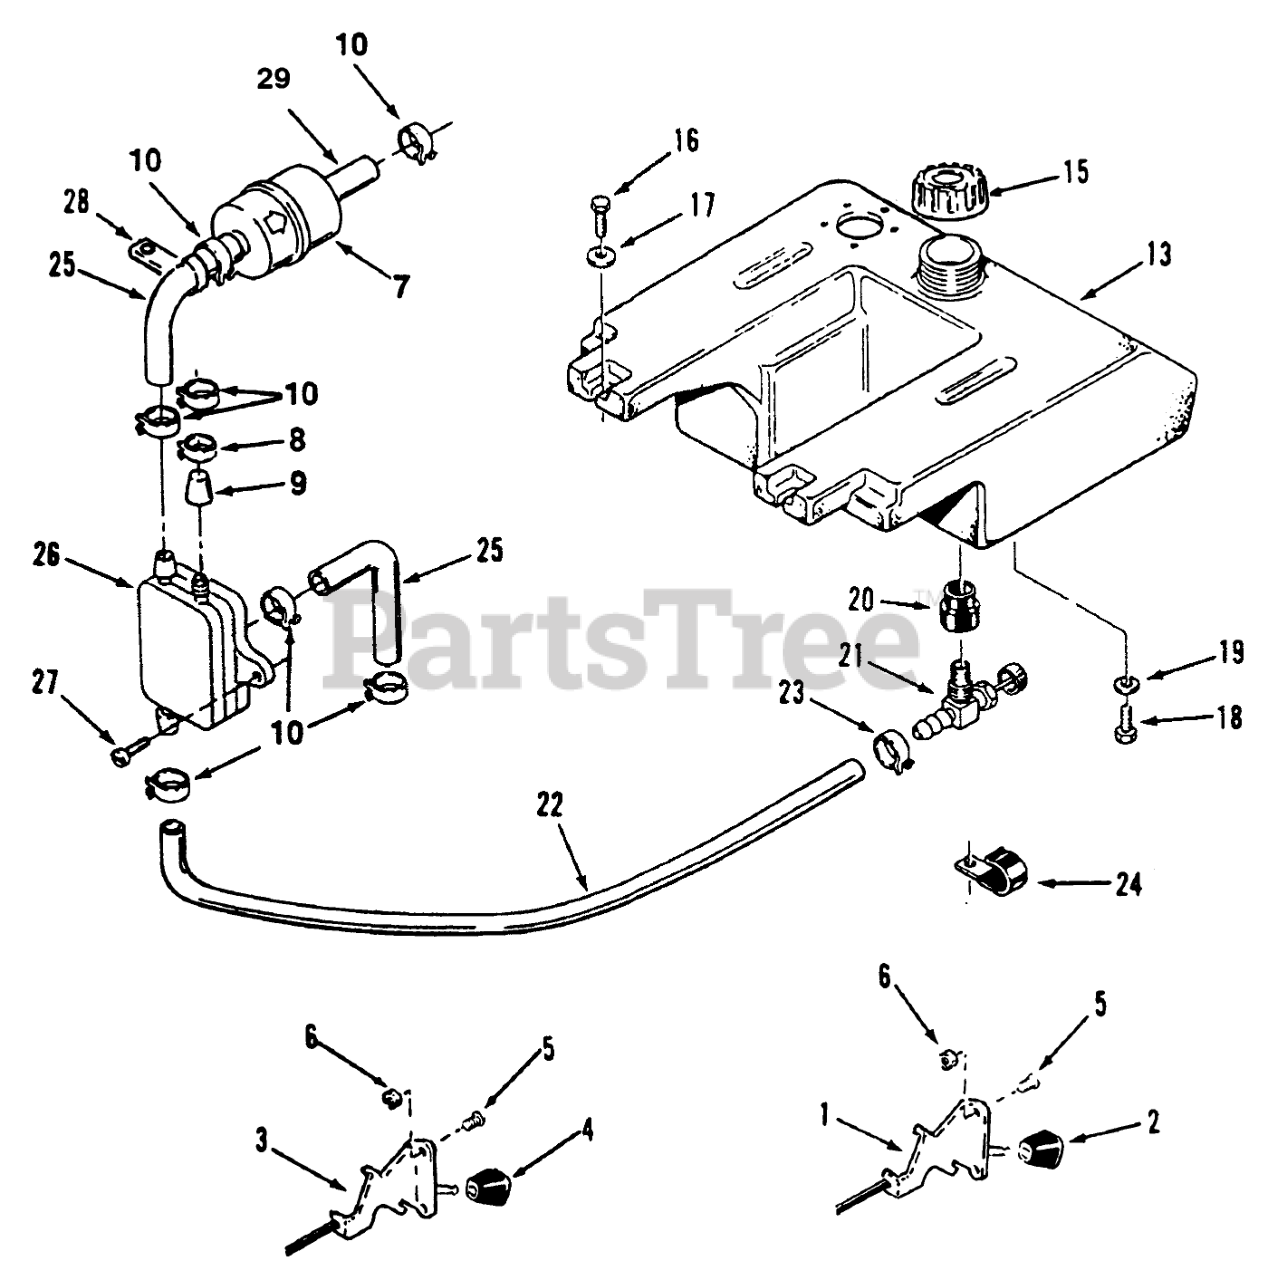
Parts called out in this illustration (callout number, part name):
1	CONTROL-THROTTLE
2	KNOB-CONTROL
3	CONTROL-CHOKE
4	KNOB-CONTROL
5	Screw
6	Nut
7	Filter-Fuel
8	CLAMP
9	CAP-FUEL OUTLET
10	CLAMP-HOSE
13	Tank-Fuel (Includes Items 20 & 21)
14	GAS CAP ASM
16	Bolt
17	WASHER-FLAT
18	SCREW-HH
19	10-24 X 3/4 FIL HD MS
20	BUSHING
21	VALVE-FUEL
22	Line-Fuel 53"
23	Clamp
24	Clamp
25	Hose
26	PUMP-FUEL
27	SCREW-TAPPING PAN HD
28	Clip
29	FUEL HOSE
